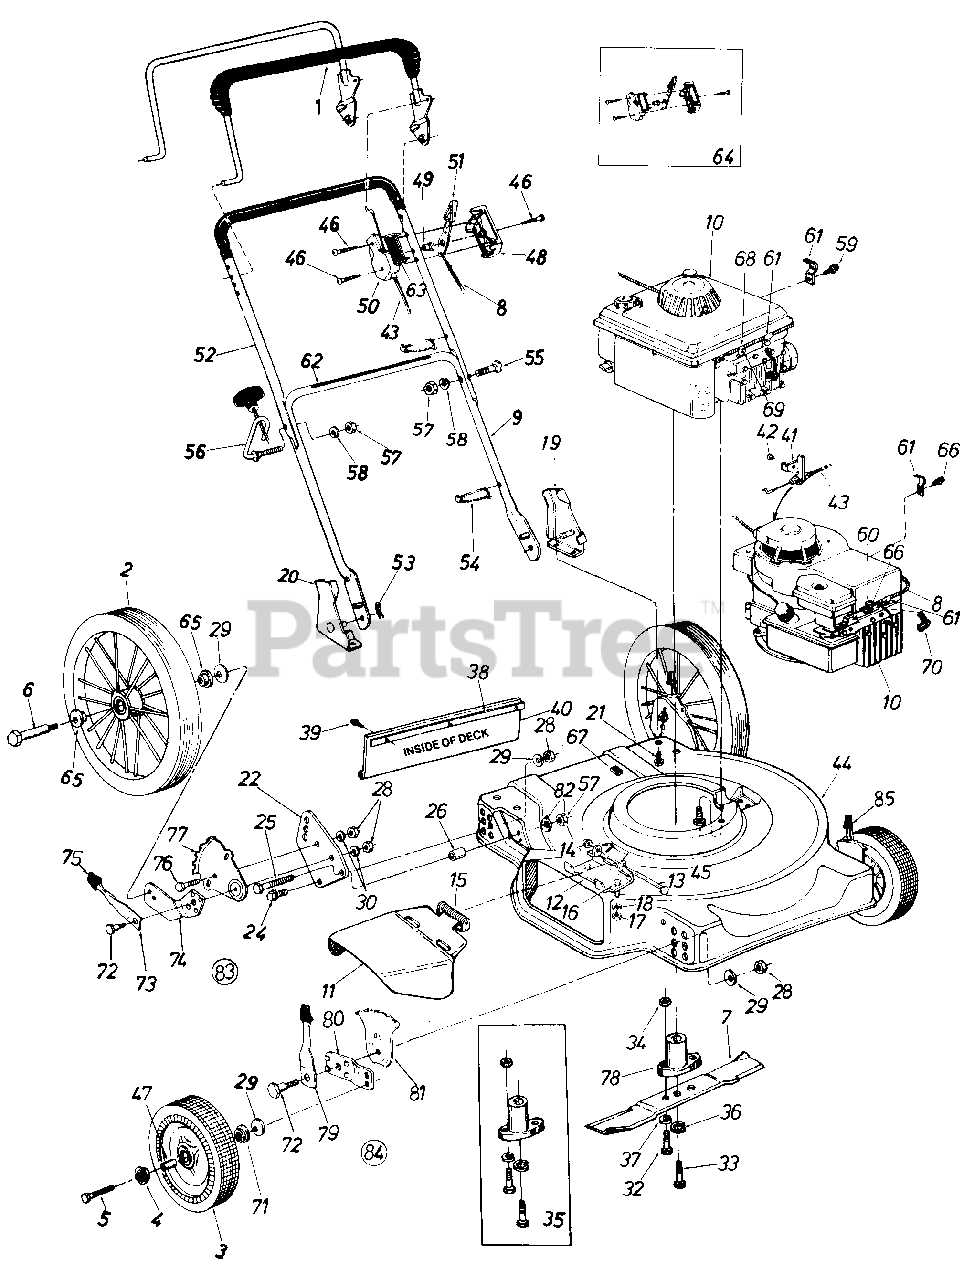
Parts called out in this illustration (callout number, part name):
1	Control Handle Ass'y.
2	Rear Wheel Ass'y.-Comp. 14.0 x 1.75
4	Bearing
5	Front Axle Bolt
6	Rear Axle Bolt
7	22" Blade
8	Throttle Wire-58" Lg.
9	Lower Handle (Chrome)
10	Engine
11	Chute Deflector Ass'y. Comp
12	Adapter Plate
13	Pivot Pin
14	Push Nut 1/4" Rod
15	Torsion Spring
16	Hex Bolt 1/4-20 x .50" Lg.
17	Hex Nut 1/4-20 Thd.
18	L-Wash. 1/4" I.D.
19	Handle Mount Brkt.-L.H.
20	Handle Mount Brkt.-R.H.
21	Hex Wash. Hd. "B" Tap Scr. 5/16-18 x .50" Lg.
22	Mounting Plate
24	Hex Sems Bolt 3/8-16 x .62"
25	Hex Bolt 5/16-18 x 1.5" Lg.
26	Spacer
28	Hex Nut 3/8-16 Thd.
29	Bell-Wash. .400" I.D. x .88"
30	L-Wash. 3/8" I.D.
32	Hex Bolt 5/16-24 x 1.00" Lg. (Grade 5)
33	Hex Bolt 3/8-24 x 2.25" Lg. (Grade 5)
34	Hex Nut 5/16-24 Thd.
35	Blade Adapter Kit
36	L-Wash. 3/8" I.D.-H.D.
37	L-Wash. 5/16" I.D.
38	Retaining Strip
39	Hex Wash. Hd. "AB"-Tap Scr. 1/4" x.62" Lg.
40	Rear Flap Ass'y.
41	Cable Bracket
42	Pop Rivet .156 Dia. x .379
43	Control Cable-43"
44	22" Deck Ass'y
45	Hex Wash. Hd. TT-Tap Scr. 3/8-16 x 1.00" Lg.
46	Truss Mach. "B"-Tap Scr. #12 x 1.50" Lg.
47	Spacer
48	Control Panel Half
49	Control Disc Pin
50	Clutch Panel Half
51	Throttle Control Lever
52	Upper Handle (Chrome)
53	Intern. Cot. Pin 5/16" Dia.
54	Cable Tie
55	Curved Carriage Bolt 5/16-18 x 1.38" Lg.
56	Rope Guide Bolt
57	Hex Nut 5/16-18 Thd.
58	L-Wash. 5/16" I.D.
59	Hex B-Tap Scr. #10 x .38" Lg.
60	Casing Clamp
61	Casing Clamp
62	Instruction Label-Handle
63	Control Label-Throttle
64	Control Housing Comp.
65	Flange Bearing
66	Hex Wash. Hd. AB-Tap Scr. #8 x .38" Lg.
67	Plastic Plug
68	Casing Clamp
69	Hex B-Tap Scr. #10 x .62" Lg.
70	Spark Plug Boot
71	Flanged Ball Bearing
72	Shoulder Bolt .50" Dia.
73	Spring Lever
74	Pivot Bar-R.H.
75	Spring Lever Knob
76	Hex Bolt 3/8-16 x .75" Lg.
77	Index Plate
78	Blade Adapter
79	Spring Lever Ass'y. w/Knob
80	Pivot Bar
81	Height Adj. Plate
82	Bell-Wash. .345 I.D. x .88
83	Rear Height Adj. Ass'y. Comp.-R. H.
84	Front Height Adj. Ass'y. Comp.-R.H.
85	Front Height Adj. Ass'y. Comp.-L. H .
